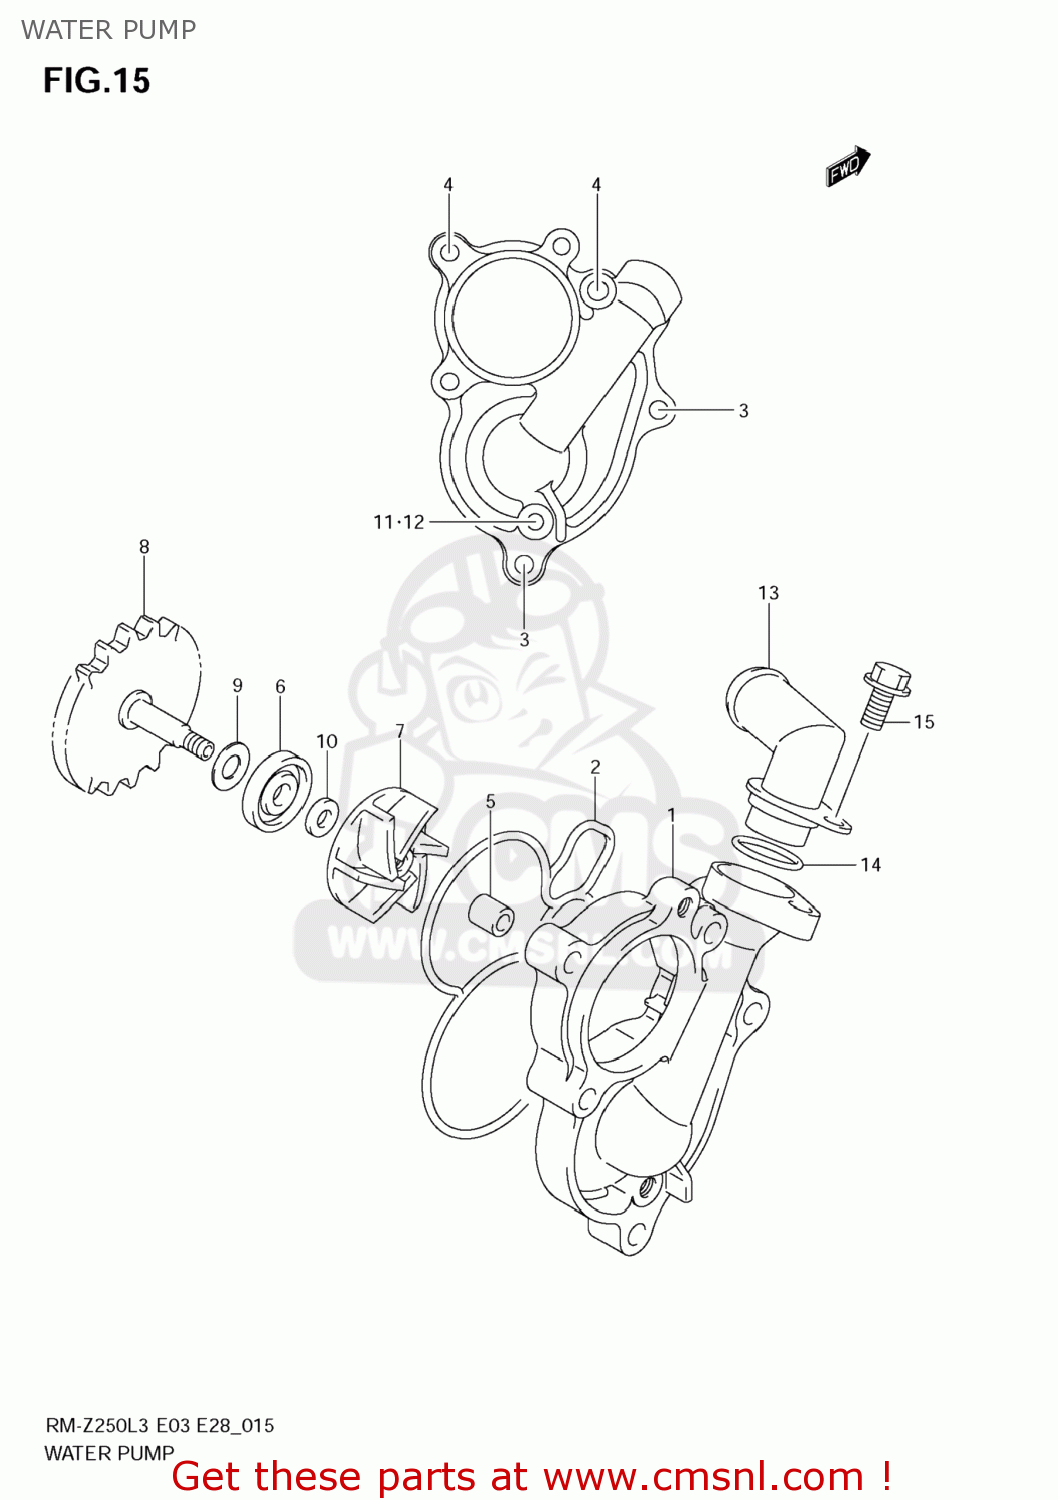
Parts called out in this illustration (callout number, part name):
1	CASE,WATER PUMP
2	O RING,WATER PUMP CASE
3	BOLT
4	BOLT
5	PIN
6	SEAL,WATER PUMP OIL
7	IMPELLER,WATER PUMP
8	SHAFT,WATER PUMP
9	SHIM(8X18X0.5)
10	SHIM(6X14X1)
11	BOLT
12	GASKET(5.8X13X1.2) (NAS)
13	JOINT,WATER PUMP
14	O RING(D:2.4,ID:16.8)
15	BOLT
